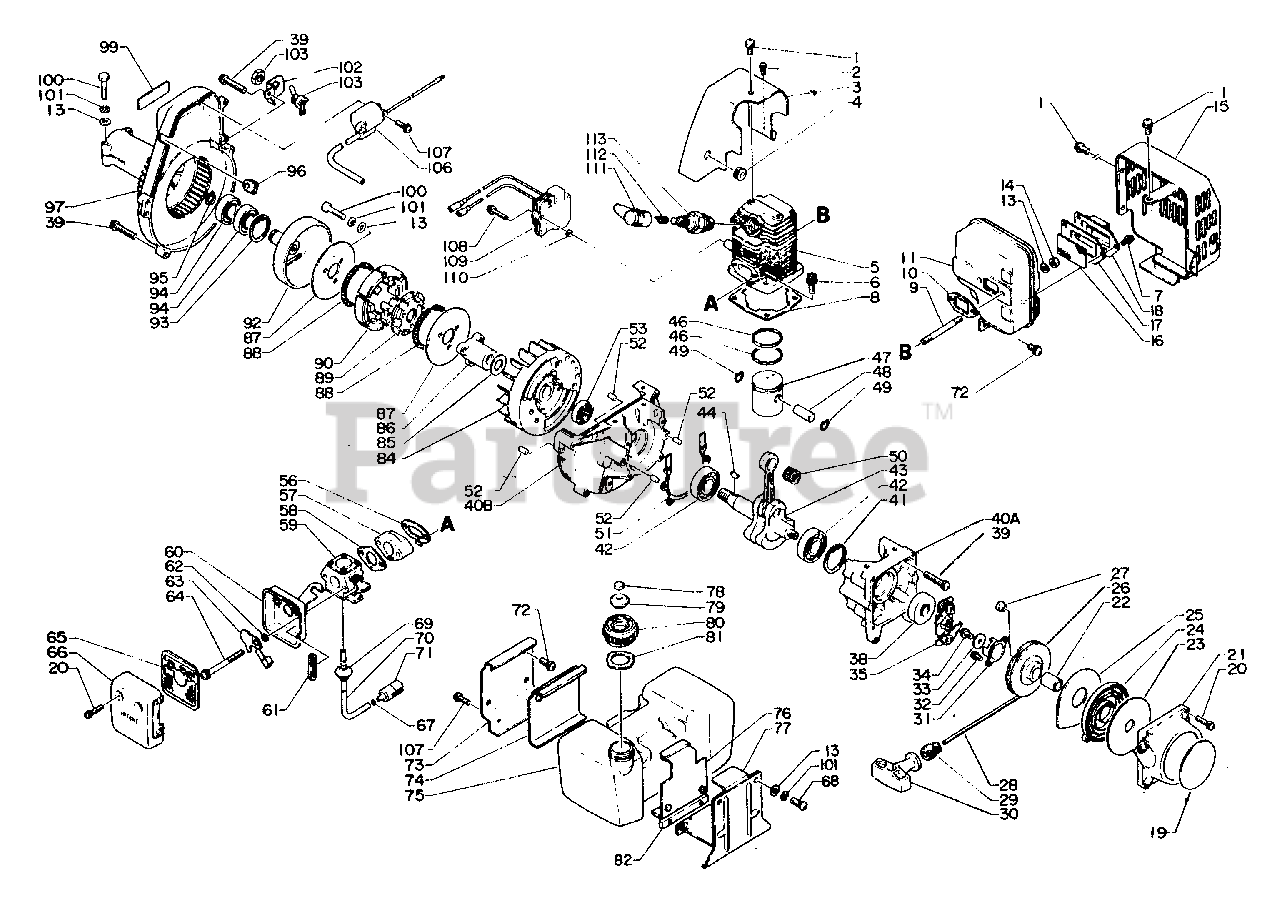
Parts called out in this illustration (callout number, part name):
1	SCREW 5×10
2	SCREW 4×10
3	COVER, CYLINDER
5	CYLINDER
6	BOLT 5×20
7	SCREW 4×8
8	GASKET, CYLINDER
9	BOLT, STUD
10	GASKET, EXHAUST
13	WASHER, FLAT 5.5×10×0.8
14	LOCKNUT - 5
15	COVER, EXHAUST
16	SCREEN, SPARK ARRESTER
17	GASKET, EXHAUST
18	LID, MUFFLER
19	LABEL - ECHO
20	SCREW 4×20
21	CASE, STARTER
23	PLATE, SIDE
24	SPRING, RECOIL
25	PLATE, SIDE
26	REEL, ROPE
27	CLIP, STARTER ROPE
28	ROPE, STARTER 3.5×850
29	GUIDE, ROPE
31	PAWL CATCHER
32	SCREW 4×8
33	WASHER 5.2×16×1.0
34	SCREW 5×10
35	STARTER PAWL ASSY
38	SEAL, OIL 18
39	SCREW 5×30
40	CRANKCASE KIT
40A	CRANKCASE KIT
40B	CRANKCASE KIT
41	RING, SNAP 35
42	BEARING, BALL 6202
43	CRANKSHAFT ASSY
44	KEY, WOODRUFF
46	RING, PISTON
47	PISTON
48	PIN, PISTON
49	RING, SNAP 8
50	BEARING, NEEDLE
51	GASKET, CRANKCASE
52	PIN, LOCATING 5×10
53	SEAL, OIL
56	GASKET, INTAKE
57	INSULATOR, INTAKE
58	GASKET, INTAKE
59	CARBURETOR - WA-106
60	CASE, AIR FILTER
62	WASHER 5.2×8×0.8T
63	SHUTTER, CHOKE
64	SCREW 5×60
65	FILTER, AIR
66	COVER, AIR FILTER
67	CLIP
68	SCREW 5×14
70	PIPE, FUEL
71	FILTER, FUEL
72	SCREW 5×14
73	BRACKET, FUEL TANK
74	CUSHION
75	TANK, FUEL
77	BRACKET
78	FILTER, CHECK VALVE
79	VENT ASSY
80	CAP
82	SPACER
84	FLYWHEEL
85	WASHER
86	ADAPTER
87	PLATE, SIDE
88	SPRING, CLUTCH
89	BOSS, CLUTCH
90	SHOE, CLUTCH
92	DRUM, CLUTCH
93	RING, SNAP 35
94	BEARING, BALL 6203
95	RING, RETAINING 15
97	CASE, FAN
98	SCREW 5×25
99	LABEL
100	BOLT - 5×25
101	WASHER, SPRING 5
102	BRACKET, SWITCH
103	SWITCH, IGNITION
106	COIL, IGNITION
107	SCREW 4×14
108	SCREW 4×22
109	COIL, IGNITION
111	CAP, SPARK PLUG
112	TERMINAL, SPARK PLUG
113	SPARK PLUG - BPM7A
